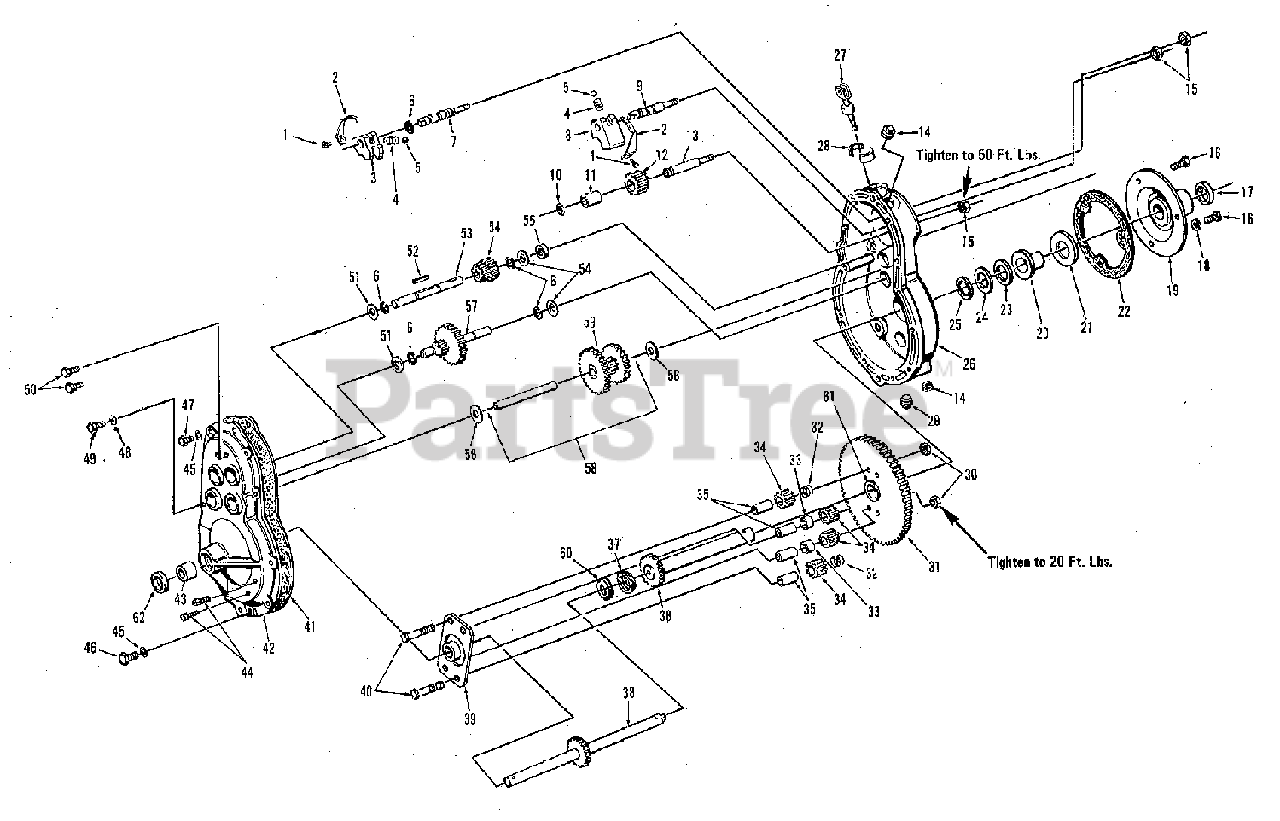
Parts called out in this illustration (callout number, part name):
1	SCREW, Hex, Head, 5/16-18 x 5/16
3	FORK, Shift, Reverse
5	BALL, Shift Lock
6	RING, Retaining
7	SHAFT, Shift, Reverse & Lo
8	FORK Shift, I & II
9	SHAFT, Shift, Hi-Lo
11	BEARING, Roller
12	PINION, Reverse
13	SHAFT, Reverse Pinion
16	SCREW, Hex Head, 3/8-16 x 7/8
18	WASHER, Lock, 3/8
19	PLATE SUPPORT ASSEMBLY
26	CASE, Gear Sub Assembly
27	SHIFT ROD ASSEMBLY
28	BUSHING, Ball, Half
30	NUT, Hex 3/8-16
32	SPRING, Thrust
33	SPACER, Differential
34	PINION, Differential
35	SPINDLE, Pinion Differential
36	AXLE TUBE & BUSHING ASSEMBLY
38	AXLE ASSEMLY
39	PLATE ASSEMBLY, Differential
40	SCREW, Hex Head, 3/8-16 x 2-1/2
41	GASKET, Case
42	COVER, Gear Case Sub-Assembly
44	SCREW, Socket Head, 3/8-16 x 3/8
45	WASHER, Lock, 5/16"
46	SCREW, Hex Head, 5/16-18 x 1-1/2
47	SCREW, Hex Head, 5/16-18 x 1-1/4
48	WASHER, Flat, 3/8
49	SCREW, Hex Head, 3/8-16 x 5/8
50	SCREW, Hex Head, 7/16-14 x 3/4
53	SHAFT, Pulley
54	PINION ASSEMBLY, Hi-Lo
57	GEAR & SHAFT ASSEMBLY
58	SHAFT & GEAR ASSEMBLY
59	CLUSTER GEAR
